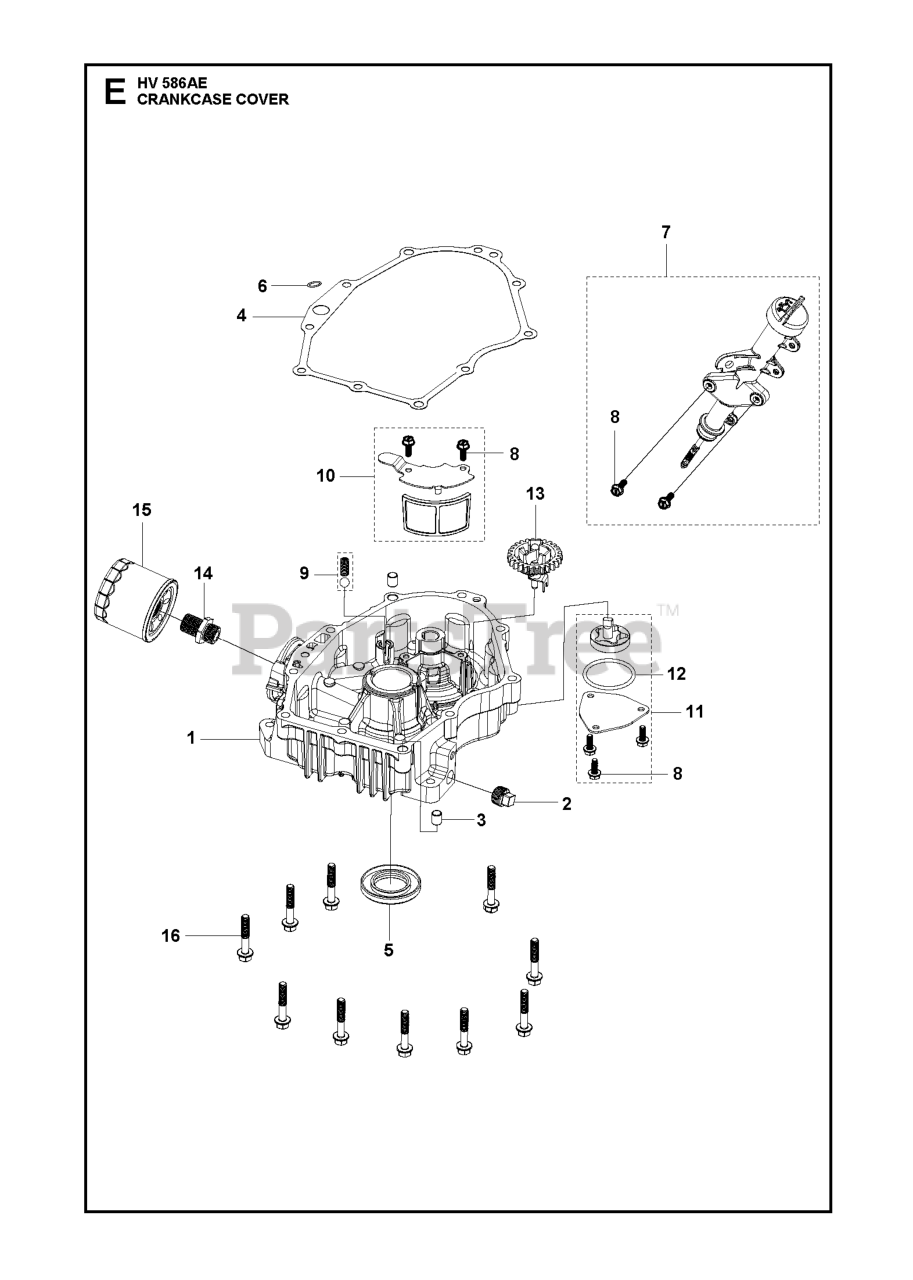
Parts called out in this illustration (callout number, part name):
2	OIL PLUG OIL PLUG
3	PIN LOCATION PIN
6	SEALING RING SEAL RING
14	OIL PLUG OIL FILTER MOUNTING P
15	FILTER OIL FILTER (ENG.452)
